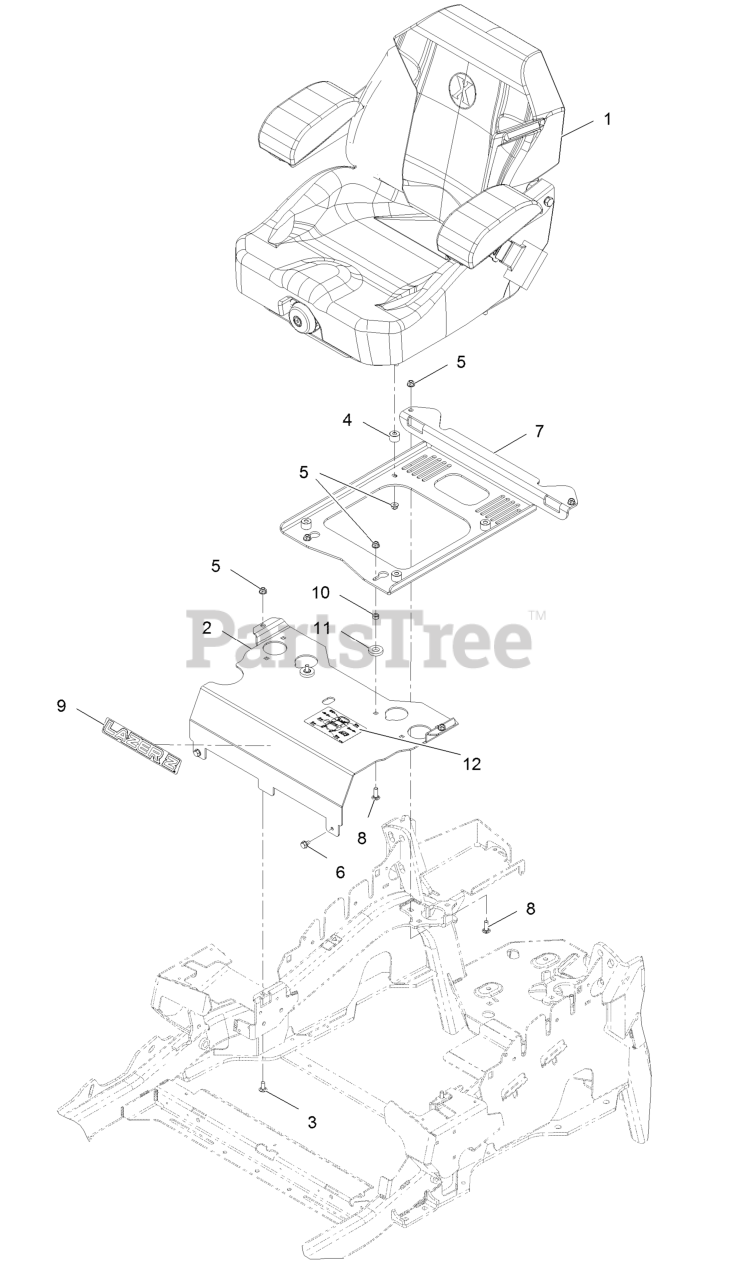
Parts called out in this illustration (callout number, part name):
1	Kit-Suspension Seat
2	Panel-Front, Seat Mount
3	Bolt-Carriage 5/16-18 X 3/Short Neck
5	Nut-Nyloc 5/16-18 Flg
6	Screw-HWH 5/16 X 1/2 Tf
7	Plate-Support, Seat
8	Bolt-Carriage 5/16-18 X 1 Sp
9	Decal, Lazer Model
10	Nut-Hex 5/16-18
11	Spacer-Blade Drive
12	Decal-Service Aid
